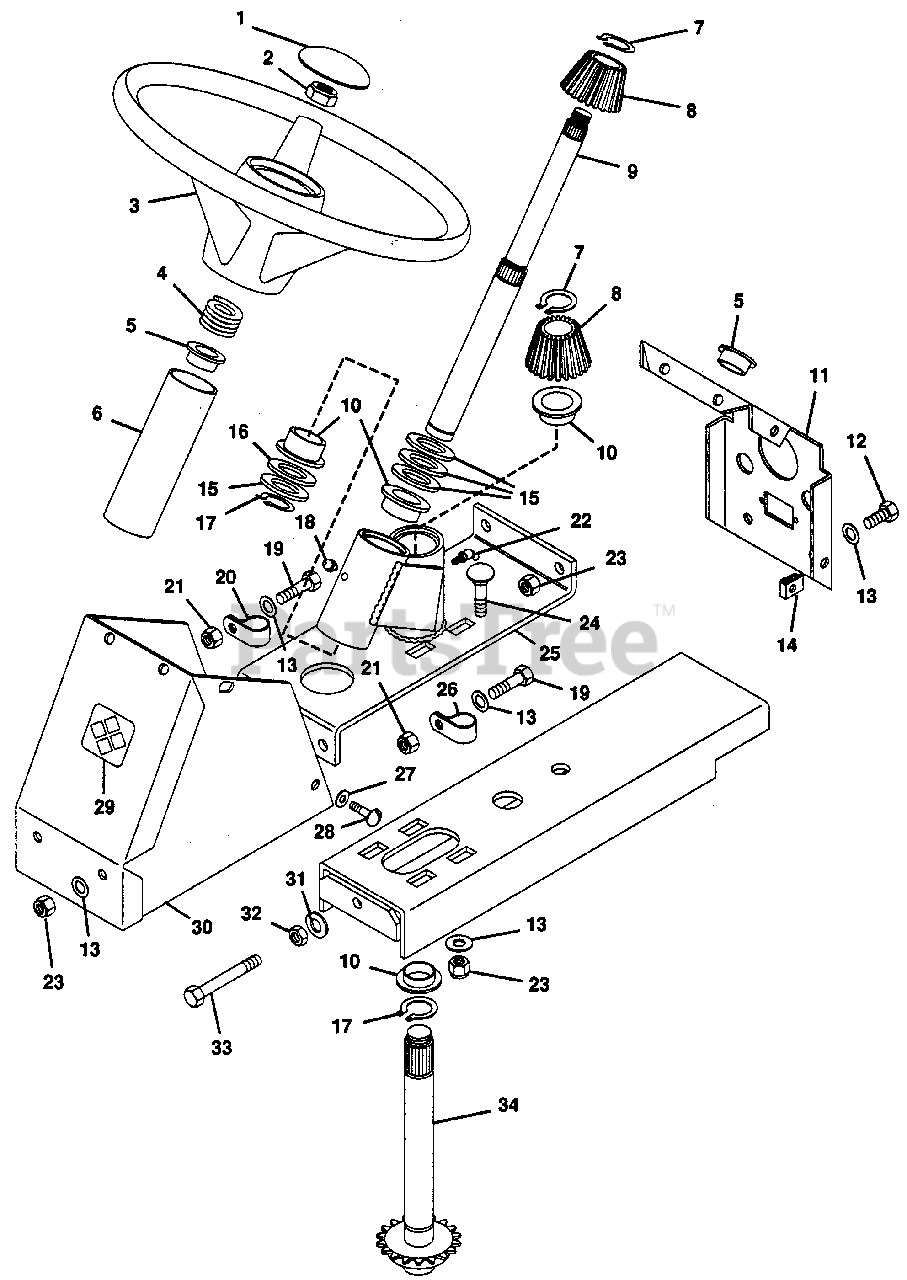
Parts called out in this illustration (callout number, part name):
1	Cap, Steering Wheel
2	Nut, Jam 5/8-11
3	Wheel, Steering
4	Spring, Comp. 1x.80x36 lb/in
5	Bushing, Nylon .76x1.00x.6 Flg.
6	Bushing, Steering Wheel
7	Ring, Retaining .875 Shaft
8	Pinion, Bevel
9	Shaft, Steering Wheel
10	Bearing, Flanged
11	Panel, Silk Screen
12	Bolt, Hex 3/8-16x.875
13	Washer, Flat .406x.812x.065
14	Nut, Retainer
15	Race, Bearing Thrust
16	Bearing, Thrust Race
17	Ring, Retaining
18	Fitting, Lube 1/4-28
19	Bolt, Hex 3/8-16x1.375
20	Clamp
21	Nut, Hex 3/8-16
22	Fitting, Lube 90 Degree
23	Nut, Lock 3/8-16
24	Bolt, 3/8-16x1.00 Rd Hd Sq Nk
25	Weldment, Steering Tube
26	Clamp, Nylon
27	Washer, Flat .281x.625x.065
28	Screw, Machine 1/4-20 Pan Hd
29	Decal, Commercial Front
30	Weldment, Front Panel
31	Washer, Lock 3/8 Reg.
32	Nut, Jam 3/8-16 Hex
33	Bolt, Hex Special 3/8-16x3.00
34	Weldment, Steering
